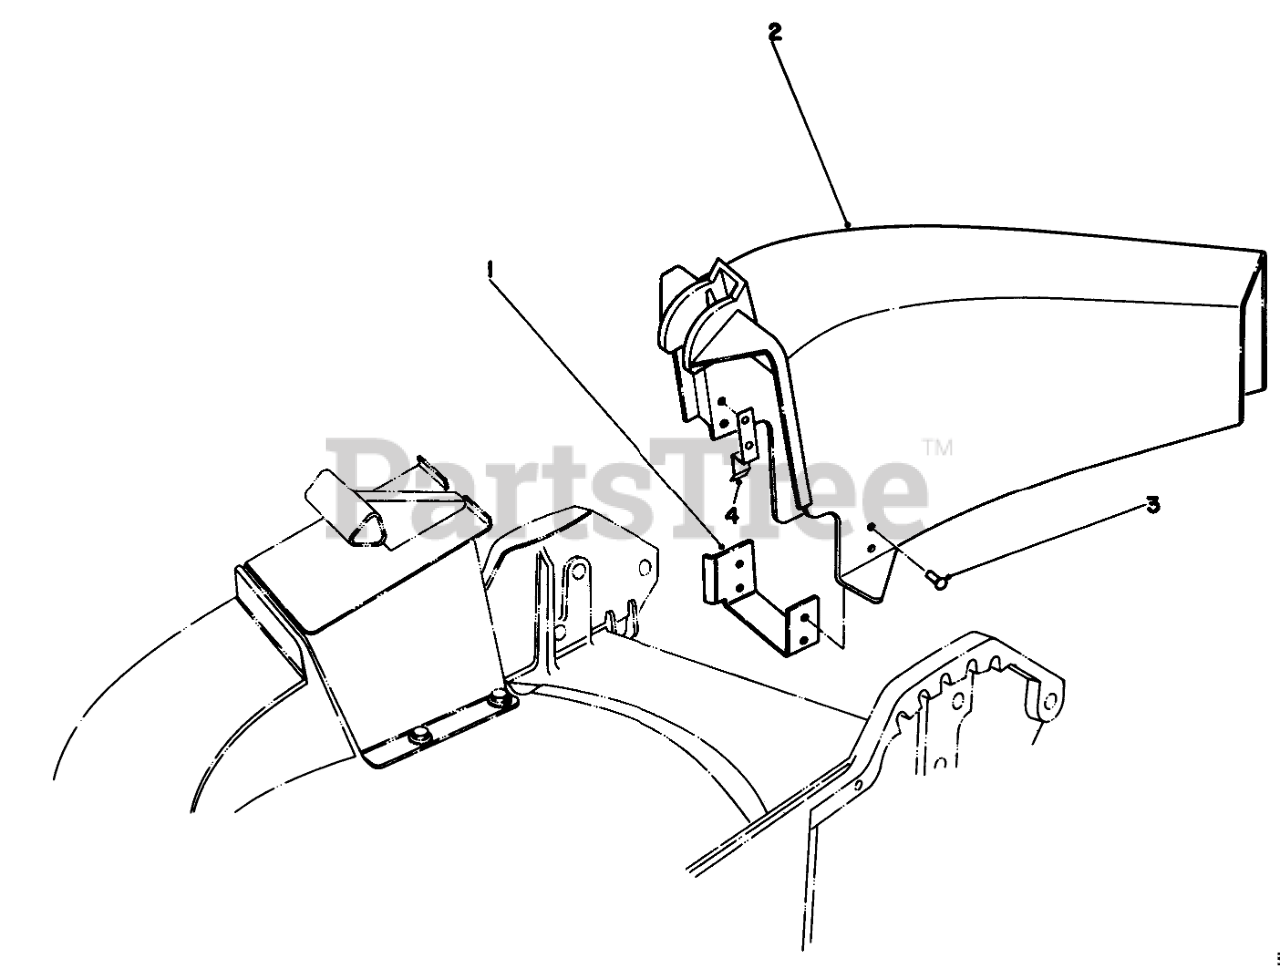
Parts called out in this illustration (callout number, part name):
1	CHUTE BRACKET
2	Chute Discharae
3	RIVET
4	CHUTE TAB
